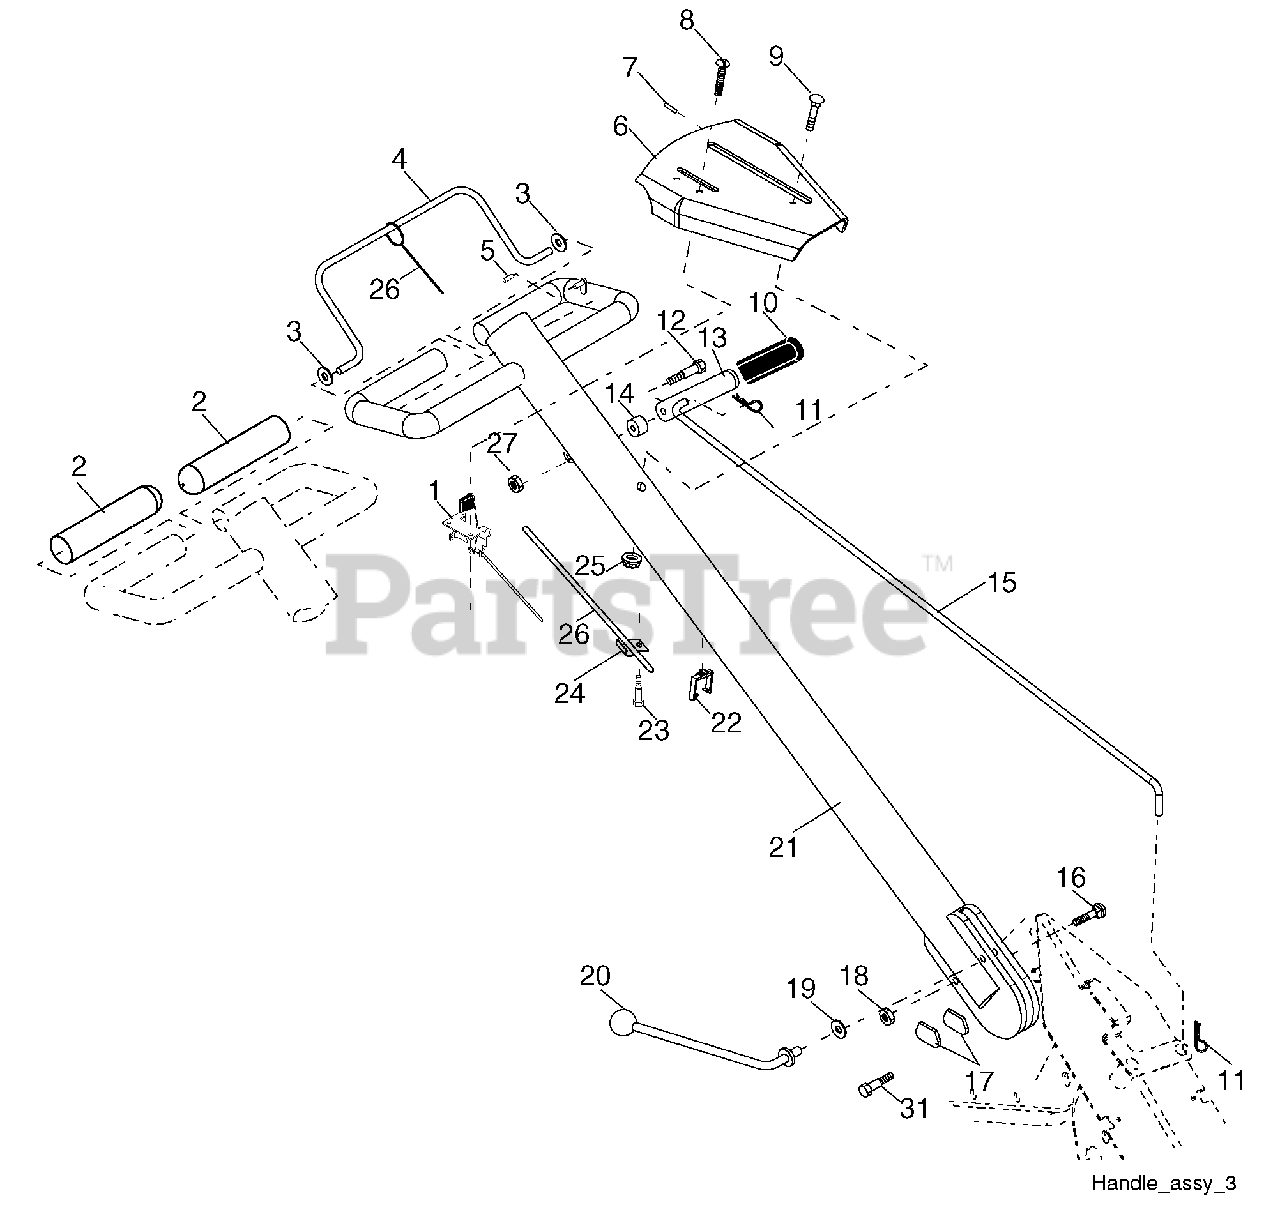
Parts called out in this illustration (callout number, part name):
1	Throttle, Control
2	Grip, Handle
3	Grommet, Handle
4	Bar, Drive Control Assembly
5	Cap, Vinyl
6	Panel, Control
7	Bushing, Split
8	Screw, Thd Cut 1/4-20 x 1/2
9	Bolt, 5/16-18 x 2-1/2
10	Handle, Grip
11	Retainer Spring
12	Bolt, Shoul der
13	Handle, Shift
14	Grommet, Rubber
15	Rod, Shift
16	Bolt 3/8-16 x 1 Gr. 5
17	Lock, Handle
18	Nut, Crownlock 3/8-16
19	Washer 13/32 x 1 x 11 Ga.
20	Lever, Lock, Handle
21	Handle, Assemble
22	Clip, Plastic, Cable
23	Screw, Hex, Washer Hd, Slotted #10-24 x 1/2
24	Clip
25	Locknut, Hex, Flange
26	Clutch, Cable
27	Nut, Lock 1/4-20
31	Bolt, Pivot
